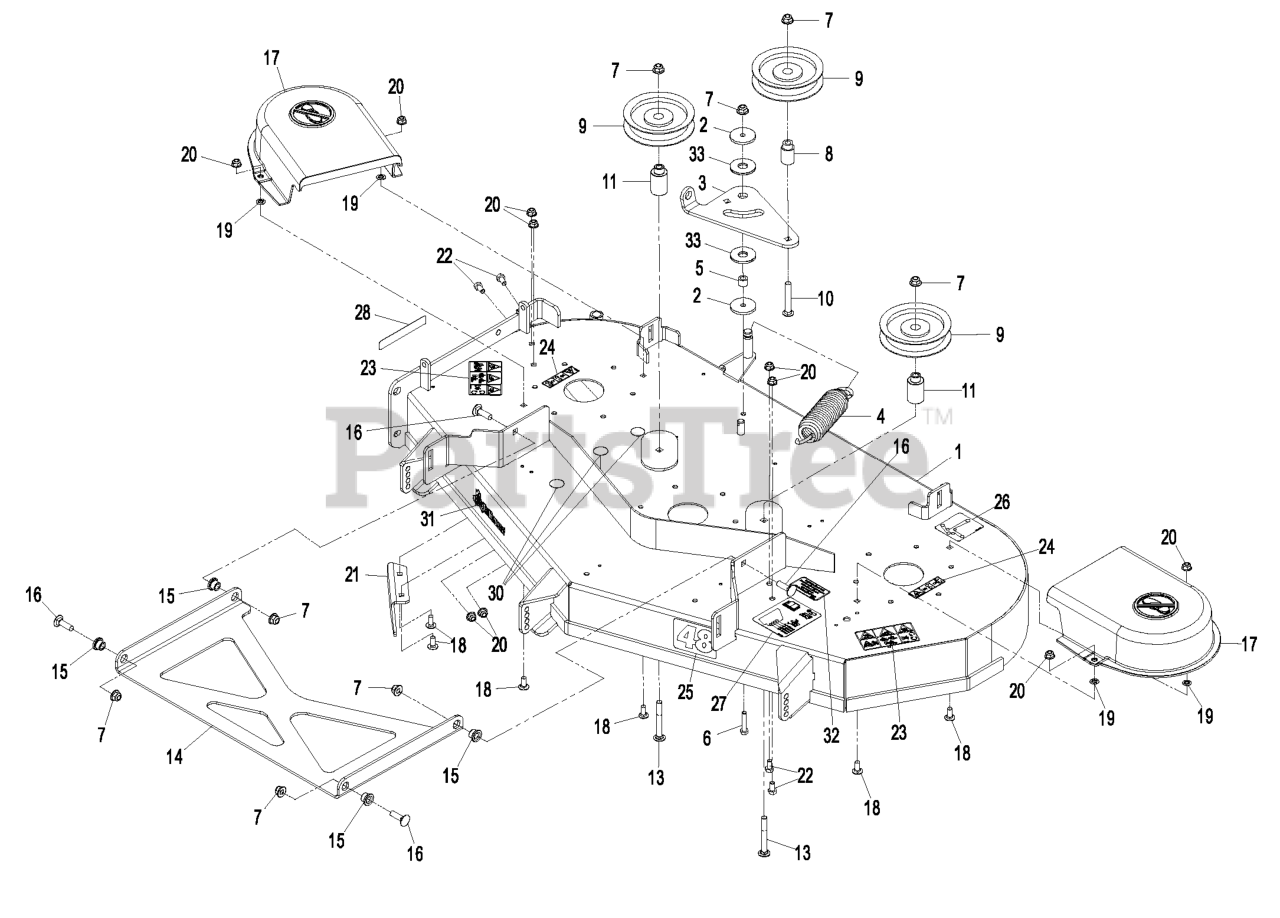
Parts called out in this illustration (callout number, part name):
1	ASM,48" DECK W/ DECAL
2	WASHER-PLAIN
3	ARM,IDLER
5	BUSHING-LEVER, LIFT
6	SCREW-HH
7	NUT-HF, NI
8	BUSHING-IDLER
10	SCREW-CARR
11	BUSHING-IDLER
13	BOLT-CARRIAGE
14	STRUT-DECK
15	BUSHING-FLANGED
16	BOLT-CARR
17	SHIELD-BELT
18	SCREW-CARR
19	RING-RETAINING, BOLT
20	NUT-HF, NI
21	BAFFLE-DISCHARGE
22	SCREW-HH
23	DECAL-DANGER
24	DECAL-WARNING, BELT SHIEL
25	DECAL,DECK 48
26	DECAL-ROUTING, BELT
27	DECAL-ROLLER, ANTI-SCALP
28	DECAL-DANGER
30	DECAL-HOLE COVER
32	DECAL,BLADE TORQUE
33	WASHER-FRICTION, COMPOSIT
